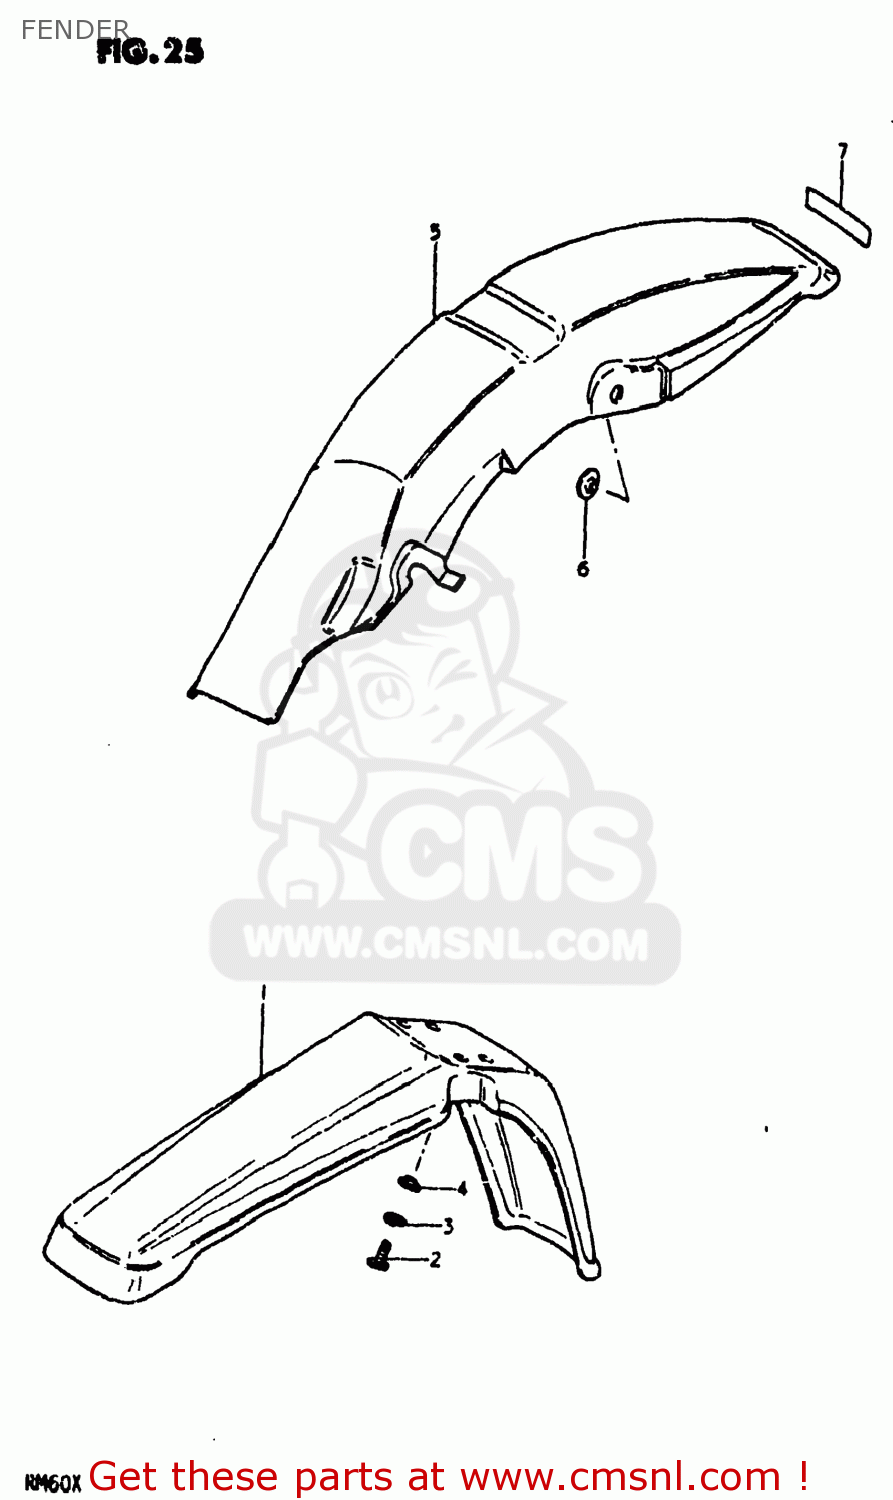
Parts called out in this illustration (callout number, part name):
1	FENDER,FRONT
2	BOLT, UPPER
3	LOCK WASHER
4	SPACER
5	FENDER,REAR
6	WASHER
7	EMBLEM,FRONT FENDER
